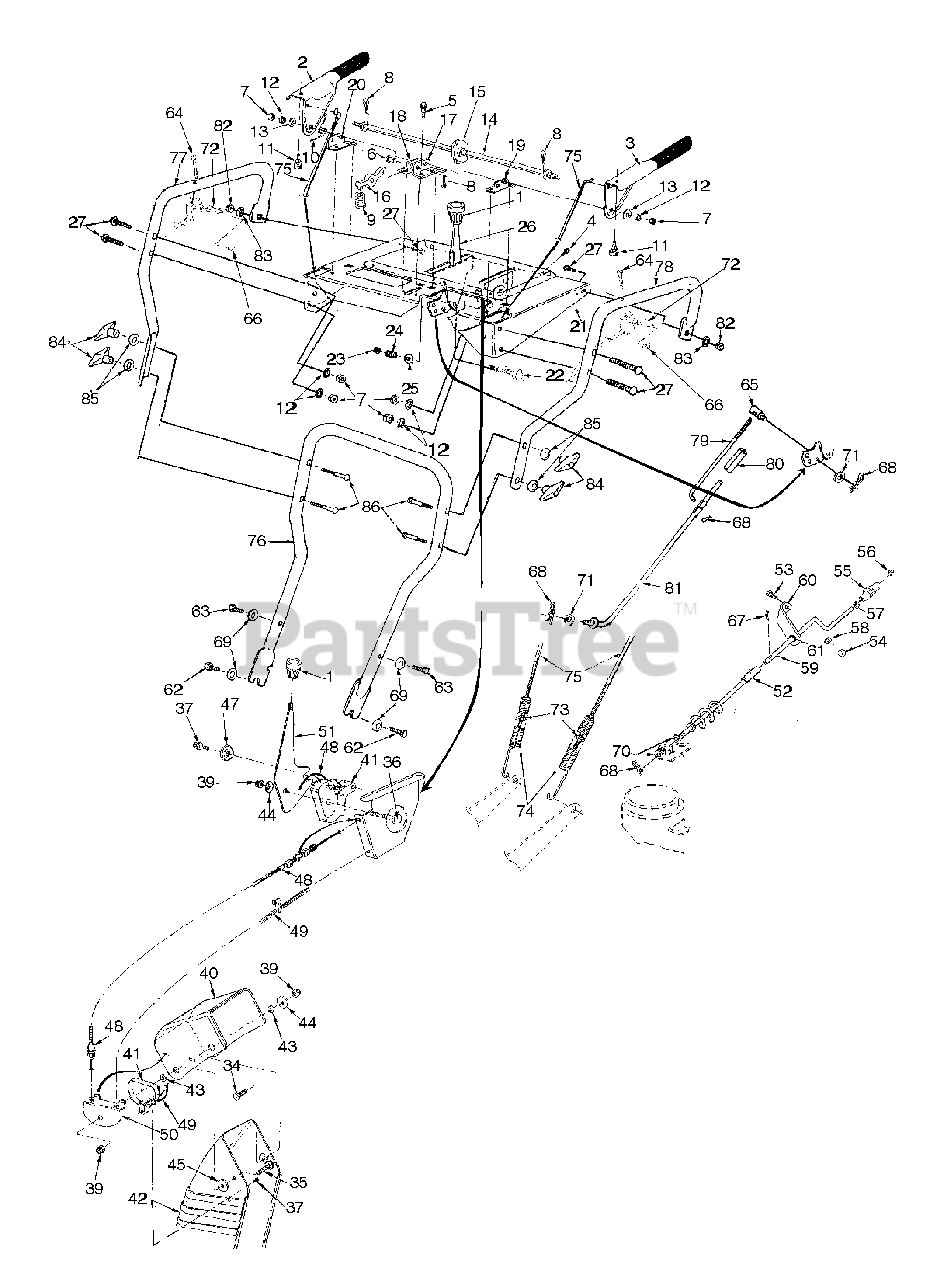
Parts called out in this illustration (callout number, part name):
1	Sml Shift Knob
2	Engage Handle RH
3	Engage Handle LH
4	Pan Head B-tapp Scr #10 x .5
5	Hwhd Sf-tap Scr 1/4-20 x 1/2 Lg.
6	Clevis Pin .31 Dia x 1.0
7	Nut Hex 5/16-18 Gd 5
8	Cot-pin 3/32 Dia x 1.0
9	Comp Spring .36 Dia x 1.0 Lg
10	Spring Torsion .44 ID
11	Rubber Bumper .63 Dia
12	Lock Washer 5/16
13	Wsher Spcl. .345 Sq. x .72 OD
15	Clutch Lock Cam
16	Clutch Lock Pawl
22	Scr Hex Cap 3/8-24 x 1.5 Gd 5
23	Hex Ins L-nut 3/8-24
24	Compression Spring .39 ID x .88
25	Bell Wash .40 ID x .88 OD x .06
34	Carriage Bolt 5/16-18 x 1.00
35	Carriage Bolt 5/16-18 x 1.75
36	Hex Scr 5/16-18 x 1.5
37	HWHD B Tapp Scr 1/4 x 5/8 Zn
39	Hex Ins L-nut 5/16-18
40	6" Upper Chute Remote Tilt
41	Chute Tilt Cable Guide
42	6" Lower Chute Remote Tilt
43	Chute Pivot Spacer
44	Fl-wash .344 ID x .88 OD x .063
45	Flt Wshr .344 x 1.125 x .125
47	Contoured Washer
48	Chute Control Cable 66"
49	Chute Control Cable 66" W/clip
54	Hex Nut 1/4-20
55	Chute Directional Control Knob
56	Push Cap 3/8 Palnut #375011
57	Flat Washer .38 ID x .60 OD x .033
58	Bell Wash .26 ID x .75 OD x .06T
61	Plastic Bushing .380 ID
62	Hex Scr 3/8-16 x .75
63	Hex Scr 3/8-16 x 1.75
64	Scr Oval C/sunk #10-24 x 1.75
65	Adjustment Ferrule
66	#10-24 Flat Weld Nut
67	Internal Cot-pin 1/2 Dia
68	Inter Cot-pin 5/16 Dia
69	Bell Wash .4 ID x .88 OD x .06
70	Fl-wash .406 ID x .74 OD x .063
71	Fl-wash Sae .34 x .68 x .062
72	Trigger Ass'y Steer
73	Hex Ins L-nut 1/4-20
74	Extension Spring
75	Cable Clutch Drive
76	Handle Lower
79	Upper Shift Rod 5/16 x 10.57
80	2 Pc Shift Rod Connector
81	Lower Shift Rod 3/8 x 14.75
82	Hex Nut 1/4 - 20
83	Bell Wash .26 ID x .75 OD x .06T
85	Bell Wash .345 ID x .88 OD x .060
86	Carriage Bolt 5/16 -18 x 2.5
